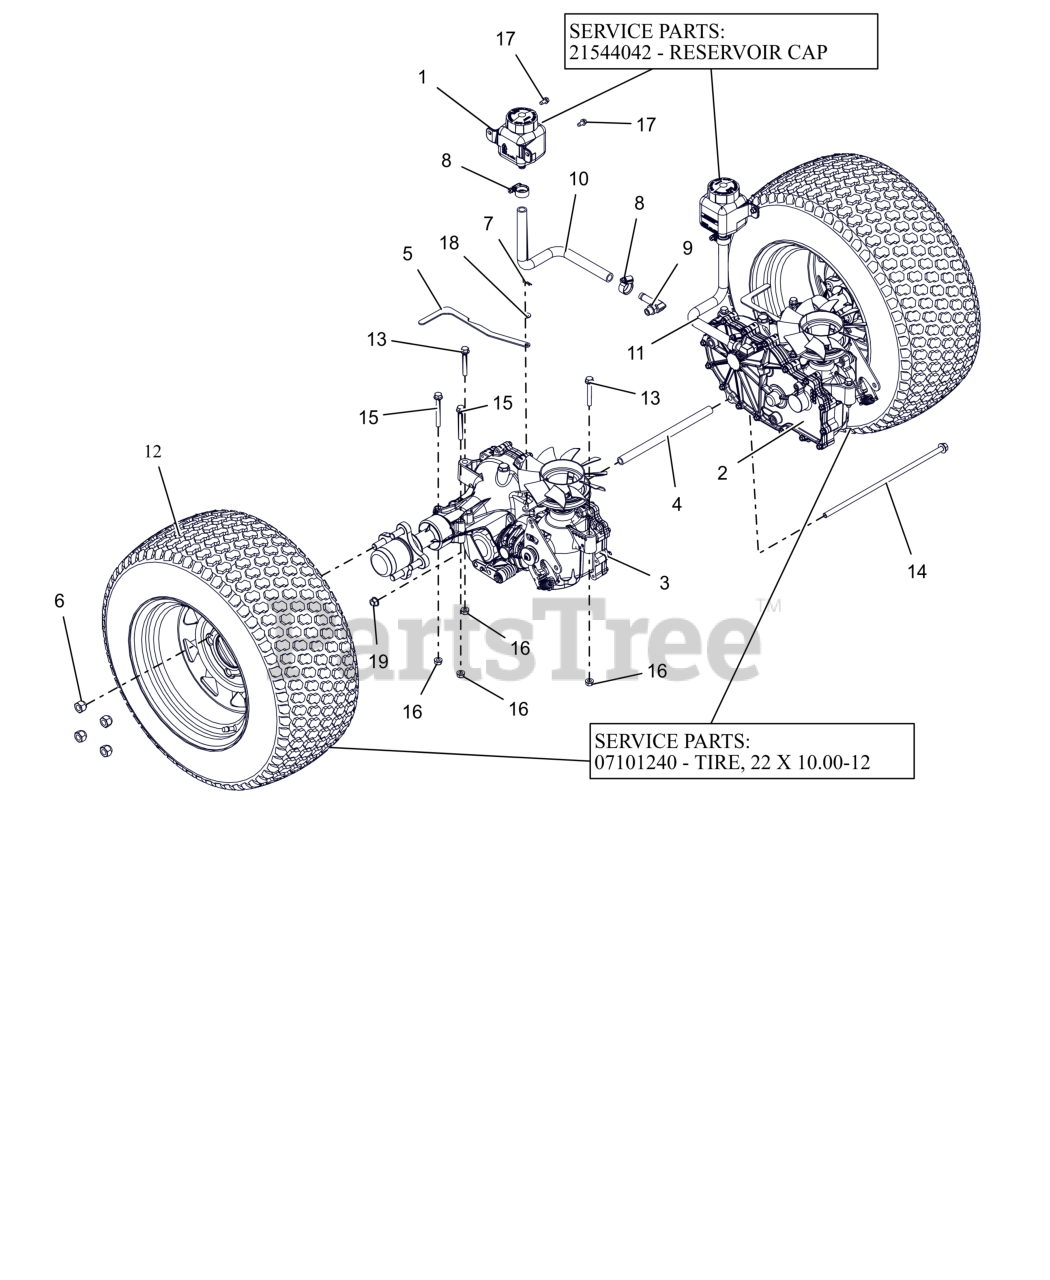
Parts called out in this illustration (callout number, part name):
1	TANK, EXPANSION
1	CAP, HYDRO RESERVOIR REPLAC.
2	TRANSAXLE, ZT3100 LH
3	TRANSAXLE, ZT3100 RH
4	SPCR, TRANSAXLE .406 ID X .630 OD X 9.95LG (BLACK)
5	BRKT, VALVE DUM
6	NUT, WHEEL .50-20 ZCC
7	PIN, HAIR #225 .072X1.09
8	CLAMP,.88 DIA. HOSE
9	FITTING, HYD (90 DEG)
10	HOSE, FORMED EXPANSION -HD RH
11	HOSE, FORMED EXPANSION -HD LH
12	ASM, WHL/TIRE 22X10.00-12 K500
12	TIRE, 22X10.00-12
13	BLT,HEX-FLG .31-18X2.25 G5 ZCC
14	BLT, HEX-FLG 0.375-16X13 GR5 ZC120
15	BLT,HEX-FLG .31-18X2.75 G5 ZCC
16	NUT,LK-CTR-FLG .31-18 GF ZCC
17	SCR-TAP .25-20X.50 HWH ZCC
18	WSHR,FLT .281X.625X.065 ZCC
19	NUT-LK-CTR-FLG .375-16 GF ZCC
